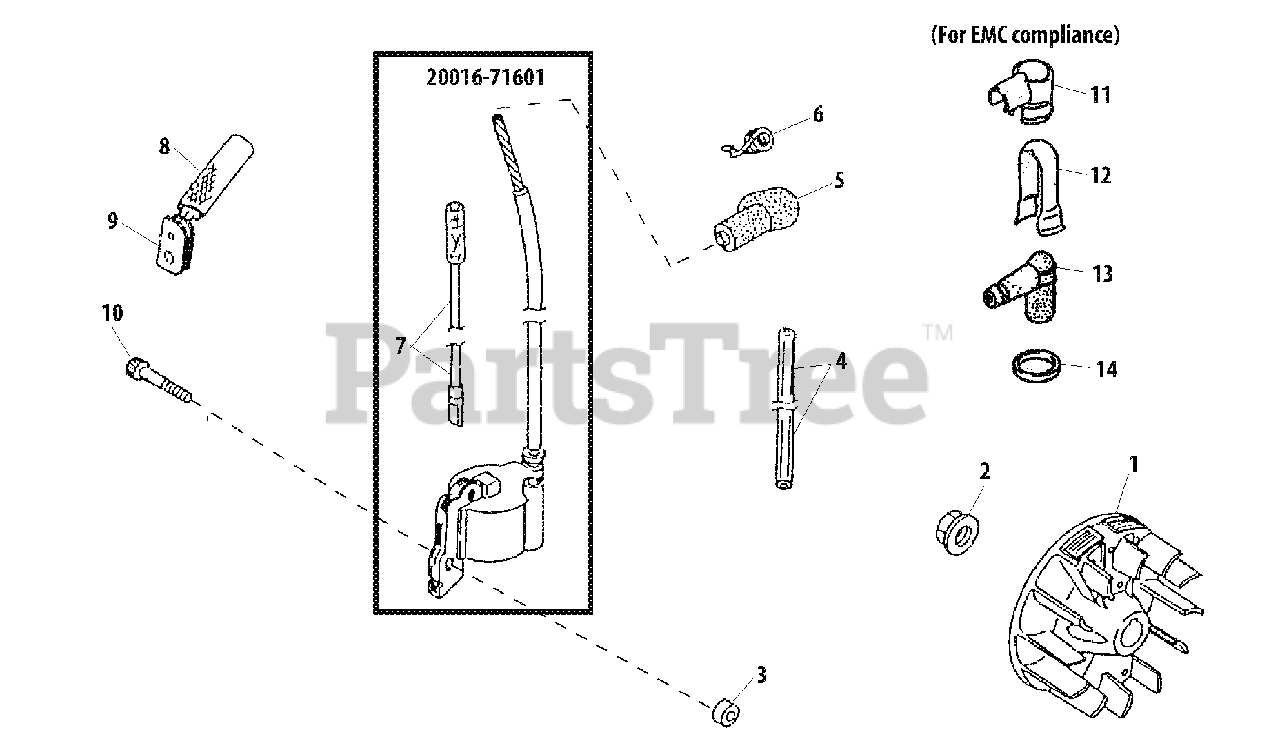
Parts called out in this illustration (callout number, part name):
1	FLYWHEEL
2	NUT - 8
3	INSULATOR
4	TUBE
5	CAP, SPARK PLUG
6	TERMINAL, SPARK PLUG CAP
7	LEAD - IGNITION
8	TUBE
9	GROMMET
10	SCREW - 4X26
11	CAP, SPARK PLUG
12	SHIELD
13	CAP, SPARK PLUG
14	SEAL, DUST
20016-71601	IGNITION COIL ASSY
